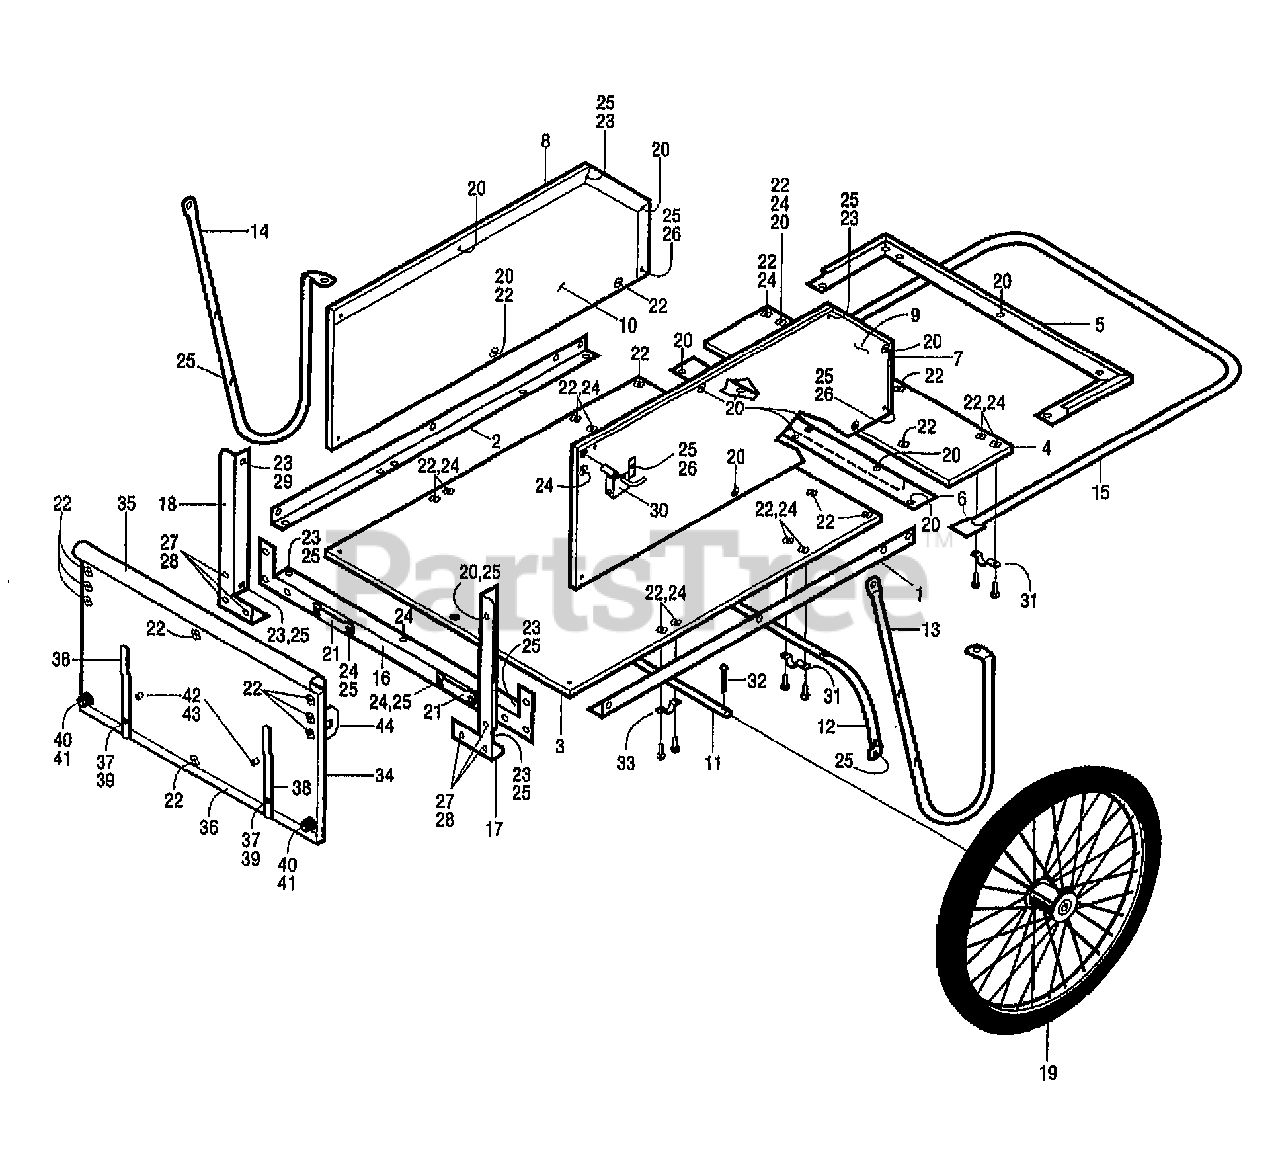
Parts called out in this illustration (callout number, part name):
1	ANGLE-26 SOLID FRONT BOT LT
2	ANGLE-BOTM 26 SOLID FRONT RT
3	PANEL-BOTTOM FRT W/TNUTS
4	PANEL-REAR BOTTOM W/TNUTS
5	PROTECTOR-M26 REAR EDGE
6	SUPT-REAR BOTTOM KM26
7	PROTECTOR-SIDE LT
8	PROTECTOR-26 TOP EDGE RT
9	PANEL-03052 LFT KM26 W/NUTS
10	PANEL-RH W/TNUTS M26
11	AXLE-MODEL 26
12	BRACE-CROSS M26
13	STAND-M26(LEG) LEFT
14	STAND-M26 (LEG) RIGHT
15	M26 HANDLE-ALL MODELS
16	SUPT-BOT 26 SWING FRONT
17	SUPT-SIDE 26 SWING FRONT LT
18	SUPT-SIDE 26 SWING FRONT RT
19	WHEEL&TIRE-COMP. M26
20	SCR-PH 1/4-20 X .5
21	PLATE-LATCH 20&26 SWING FRONT
22	NUT-HT/LK 1/4-20X.375
23	BOLT-1/4 X 1 PAN HD
24	BOLT-1/4 X 5/8 PAN HD
25	NUT-LK 1/4-20
26	BOLT-SLPH 1/4-20 X.875-ZP
27	SCR-HH 5/16-18X.5 GD5 YEL
28	NUT-H/LK 5/16-18 NYLOCK
29	PIVOT-HINGE M26 R/D
30	ASSM-20&26 PLUNGER
31	BRKT-AXLE MTG
32	PIN-COTTER 3/32 X 1 1/4
33	CLAMP-AXLE 20 & 26
34	PANEL-FRNT DOOR W/T NUTS
35	EDGE-TOP 26 SWING FRONT
36	EDGE-BOT 26 SWING FRONT
37	BOLT-SLPH 1/4-20X1.125ZP
38	LATCH-20&26 SWING FRONT
39	SPACER-20&26 SWING FRONT
40	BOLT-1/4 X 1 1/4 PAN HD
41	CASE FEET
42	BUSHING-.31X.188X.38
43	SCR-WOOD RHS M8X.75 ZP
